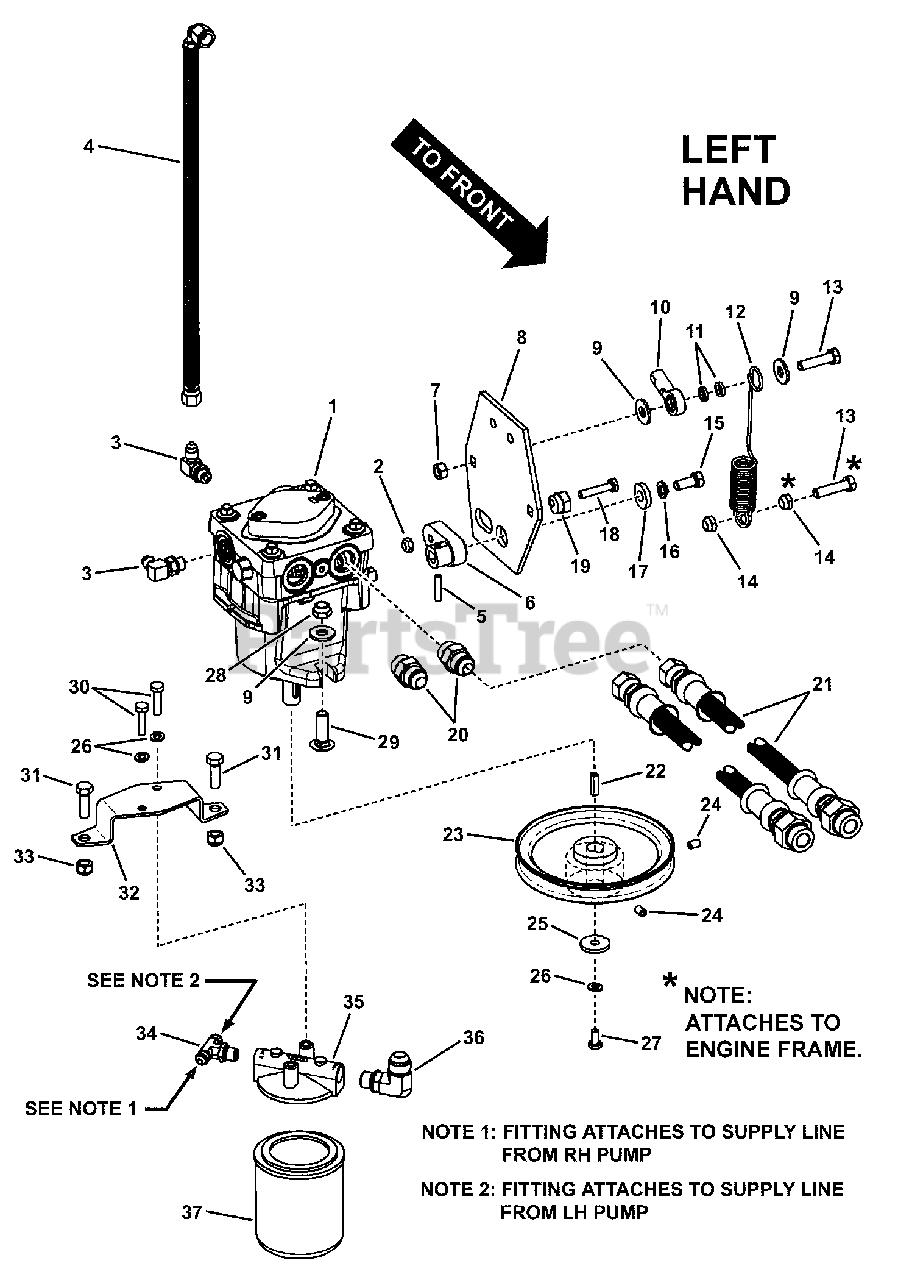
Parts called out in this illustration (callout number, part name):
1	PUMP, Hydraulic, LH, HG, Pro Ser. 3
2	NUT, 1/4-20 Hex Top Lock, GR B
3	FITTING, 90 Degree- "O"-Ring Boss
4	HOSE ASSEMBLY, Pro Hydro Series 3 (13.5" hose length)
5	ROLL PIN, 5mm x 25mm
6	ARM, Pump
7	NUT, 5/16-18 Hex Center Lock, GR 5 or B
8	SHIFT ARM, Pump
9	WASHER, 3/8" I.D. x 7/8" O.D. x 1/16" Flat
10	ROD END, Pump Control Linkage (5/16-24 thread)
11	BUSHING, Spring
12	SPRING, Hydro
13	BOLT, 5/16-18 X 1-1/4 GD5 YZ
14	NUT, 5/16-18 Hex Top Lock, GR B
15	BOLT, 5/16-18 X 3/4 GD5
16	WASHER, .32 x .58 x .08 Split Lock
17	SPACER, Blade Hub
18	SCREW, 1/4-20 x 1-1/4, Hex Head Cap, GR 5
19	ECCENTRIC
20	FITTING, Hydraulic, Straight 3/4-16 UNF
21	HOSE, Pump/Motor, High Pressure 21-1/2"
22	KEY, M5 x M20
23	PULLEY, 5.5 w/Set Screws
24	SET SCREW, 1/4-20 X 3/8" CONE
25	WASHER, 1/4" Flat
26	WASHER, 1/4" I.D. Split Lock
27	SCREW, M6 1.0X12MM, Hex Head, CZ
28	NUT, 3/8-16, HEX TOP LOCK
29	BOLT, 3/8-16 x 1-1/4" Short Neck Carriage, GR 5
30	BOLT, 1/4-20 X 1" GD5 CZ
31	BOLT, 5/16-18 X 1 GD5 YZ
32	BRACKET, Filter
33	NUT, 5/16-18 HEX NYLON LOCK
34	FITTING, Tee, 4-4-6 w/37 Degree Flare
35	FILTER HEAD
36	FITTING, 90 Degree w/37 Degree Flare
37	FILTER, OIL
